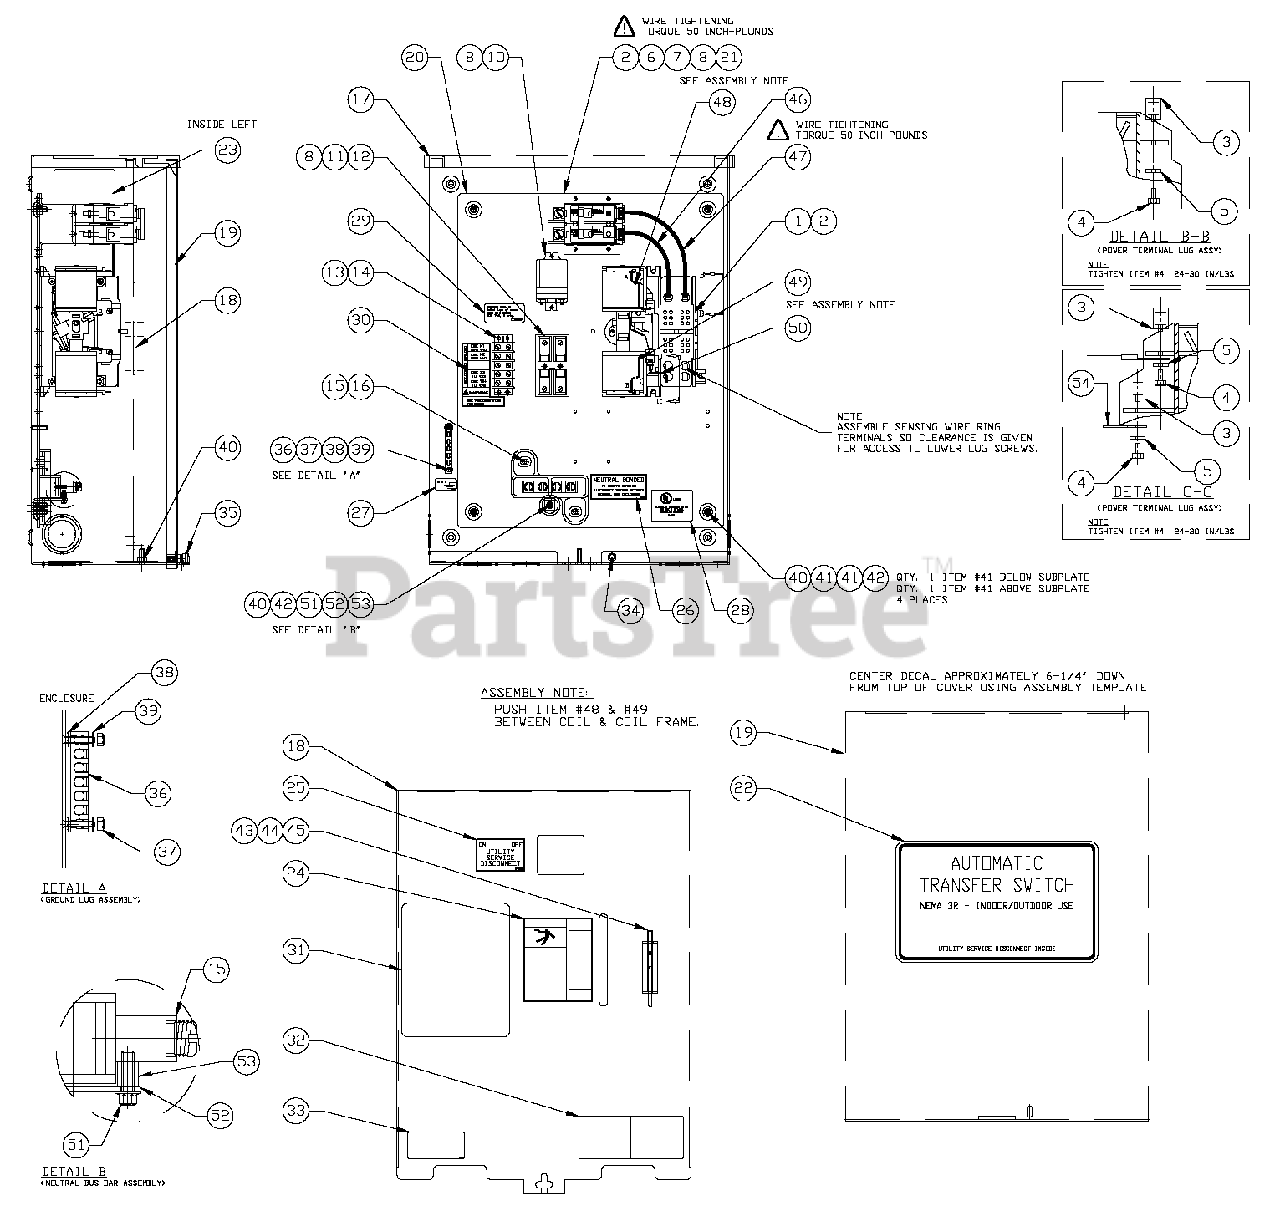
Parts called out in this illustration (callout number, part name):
1	TR SW-HSB 100A 2P 250V
2	SCREW HHTT M5-0.8 X 10 BP
3	LUG SLDLSS 1/0-#14X9/16 AL/CU
4	SCREW PPHM #10-32 X 5/16
5	WASHER, LOCK # 10
6	CB 100A 2P BACK MNT SIEMENS
7	C/BKR MOUNTING BRACKET
8	SCREW HHTT M4-0.7 X 10 BP
9	WIRING HARNESS HSB (NOTSHOWN)
10	RELAY PNL 12VDC DPDT
11	FUSEBLOCK 30A 600V 2 POLE
12	FUSE 5A X BUSS HLDR73591
13	BLOCK, TERM 20A 5 X 6
14	RIVET, POP .156 X .67
15	ASSY-NEUT BLK 100A W/TAP
16	SCREW HHTT M6-1.0 X 12 MM
17	ENCLOSURE, 100/200A TRANSFER SWITCH
18	COVER, INSIDE TRANSFER SWITCHENCL
19	COVER, TRANSFER SWITCH
20	SUBPLATE, 100/200A XFER SW
21	RISER, 100A SERVICE ENTRANCE
22	DECAL, FRNT CVR ATS 3R SER DIS
23	DECAL, XFER SW SE 100A 120/240
24	DECAL, MANUAL OPERATING HANDLE
25	DECAL, UTILITY DISCONNECT
26	DECAL, NEUTRAL CONNECTION
27	DECAL, GROUNDING LUG
28	DECAL, UL LIST HSB
29	DECAL, FUSE REPLACEMENT
30	DECAL, TERMINAL STRIP
31	DECAL, TEST SEQUENCE
32	DECAL, TERMINAL SHOCK HZD BI
33	DECAL, LIVE CIRCUIT ENG/FRN/SPN
34	NUT TRIC 1/4-20 X .525
35	THUMB SCREW 1/4-20x1/2
36	GROUND BAR (5) 4-14 AWG CONN
37	NUT HEX LOCK M4-0.7 SS NYL INS
38	WASHER SHAKEPROOF EXT #8 STEEL
39	WASHER FLAT M4
40	NUT HEX 1/4-20 SS
41	WASHER FLAT 1/4-M6 ZINC
42	WASHER LOCK M6-1/4
43	BRACKET, ARM EXTENDER
44	RIVET POP .156 X .362 AL
45	ARM EXTENDER PIN
46	WIRE ASM, 2AWG 100A 2-P T/S N1A
47	WIRE ASM, 2AWG 100A 2-P T/S N2A
50	WIRE-E1
51	SCREW HHTT M4-0.7 X 16 BP
52	BUSBAR, NEUTRAL BLOCK
53	5/16" BRASS SPACER
54	LUG DIS QK NI-S 10X45 DEG BR/T
